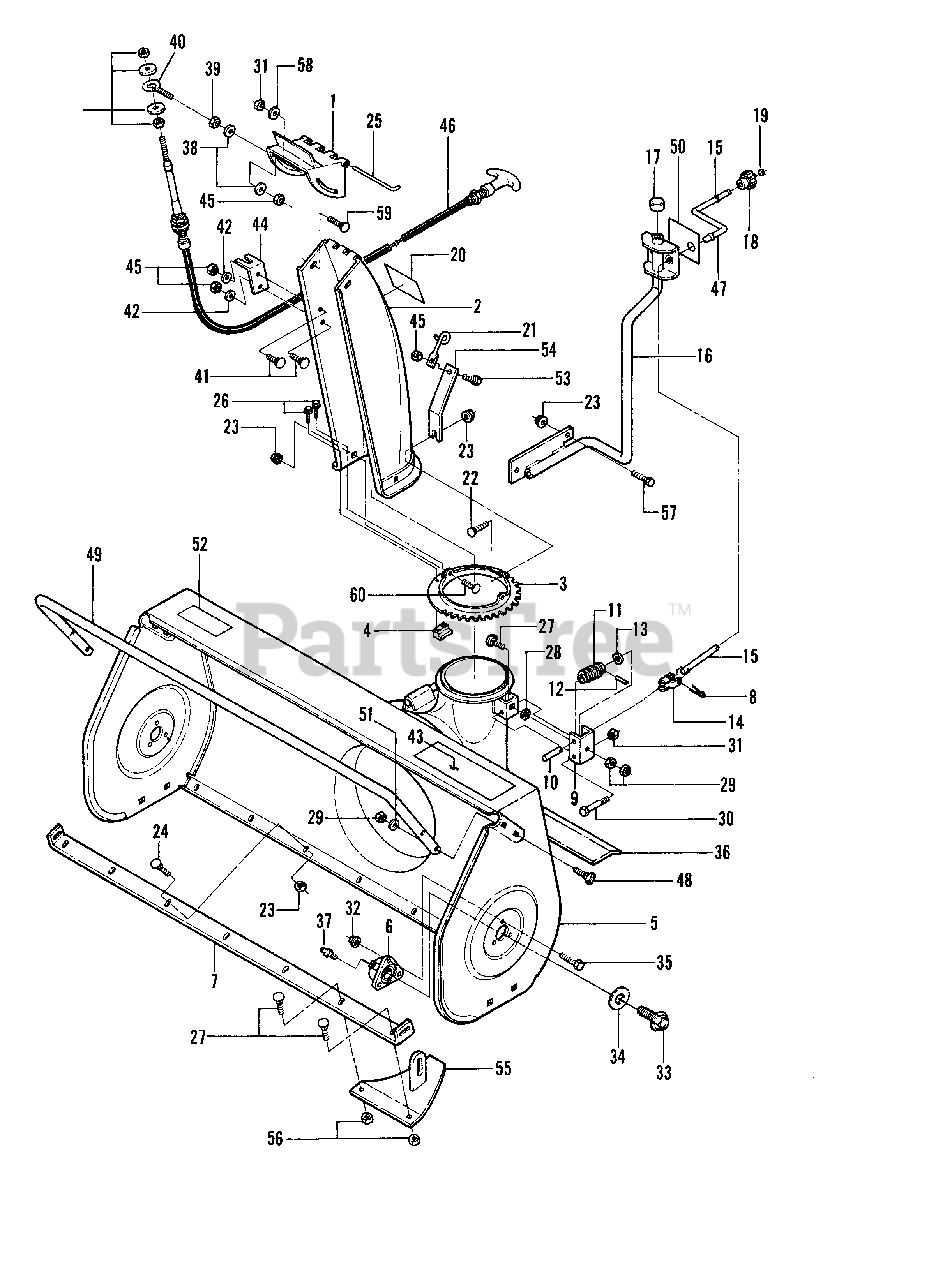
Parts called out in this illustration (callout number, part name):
1	DEFLECTOR, Discharge Chute
2	ASSEMBLY, Discharge Chute
3	RING, Chute
4	RETAINER (Chute Ring to Housing)
5	ASSEMBLY, Housing
6	BEARING, Auger Shaft
7	BLADE, Scraper
8	PIN, 1/8 x 1" Cotter
9	BRACKET, Worm
10	SHAFT, Worm
11	WORM
12	PIN, 1/8 x 3/4" Roll
13	WASHER, Spring
14	CONNECTOR
15	CRANK, Chute
16	BRACE, Chute Crank
17	CAP, Crank Brace
18	KNOB, Chute Crank
19	NUT, 5/16-18 Hex Lock
20	DECAL, Danger
21	BRACKET, Pull Rope
22	BOLT, 5/16-18 x 3/4" Short Neck (Grade 5)
23	NUT, 5/16-18 Hex Flange Lock
24	BOLT, 5/16-18 x 3/4" Carriage
25	PIN, Hinge
26	SCREW, #10-24 x 5/8" Self-Tapping
27	BOLT, 5/16-18 x 1" Carriage
28	RETAINER, 5/16 Bolt
29	NUT, 5/16-18 Hex
30	SCREW, 5/16-24 x 2-1/2" Hex Head Cap
31	NUT, 5/16-24 Hex Lock
32	NUT, 1/4-20 Hex Flange Lock
33	SCREW, 3/8-16 x 3/4" Self-Tapping
34	WASHER, 3/8" Flat
35	BOLT, 1/4-20 x 3/4" Hex Flange Lock
36	BAR, Stiffener
37	FITTING, Lube (Press fit for .187 hole-no ball)
38	WASHER, 1/4 Flat
39	NUT, 1/4-20 Hex
40	BOLT, 1/4-20 Eye
41	BOLT, 1/4-20 x 1/2" Carriage
42	WASHER, 1/4 Internal Tooth Lock
43	DECAL, SAFETY Instruction
44	MOUNT, Cable
45	NUT, 1/4-20 Hex Center Lock
46	CABLE, Control
47	BUSHING
48	BOLT, 5/16-18 x 1-1/2" Curved Head
49	CUTTER, Drift
50	DECAL, Chute Control
51	WASHER, 5/16 Split Lock
52	LOGO, SNAPPER
53	SCREW, 1/4-20 x 5/8" Hex Head Cap
54	BRACKET, Cable Guide Mounting
55	SHOE, Skid
56	NUT, 5/16-18 Hex Flange Lock
57	SCREW, 5/16-18 x 1-1/4" Self-Tapping
58	WASHER, 5/16 Flat
59	SCREW, 5/16-24 x 3/4" Hex Head Cap
60	BOLT, 5/16-18 x 5/8" Carriage
